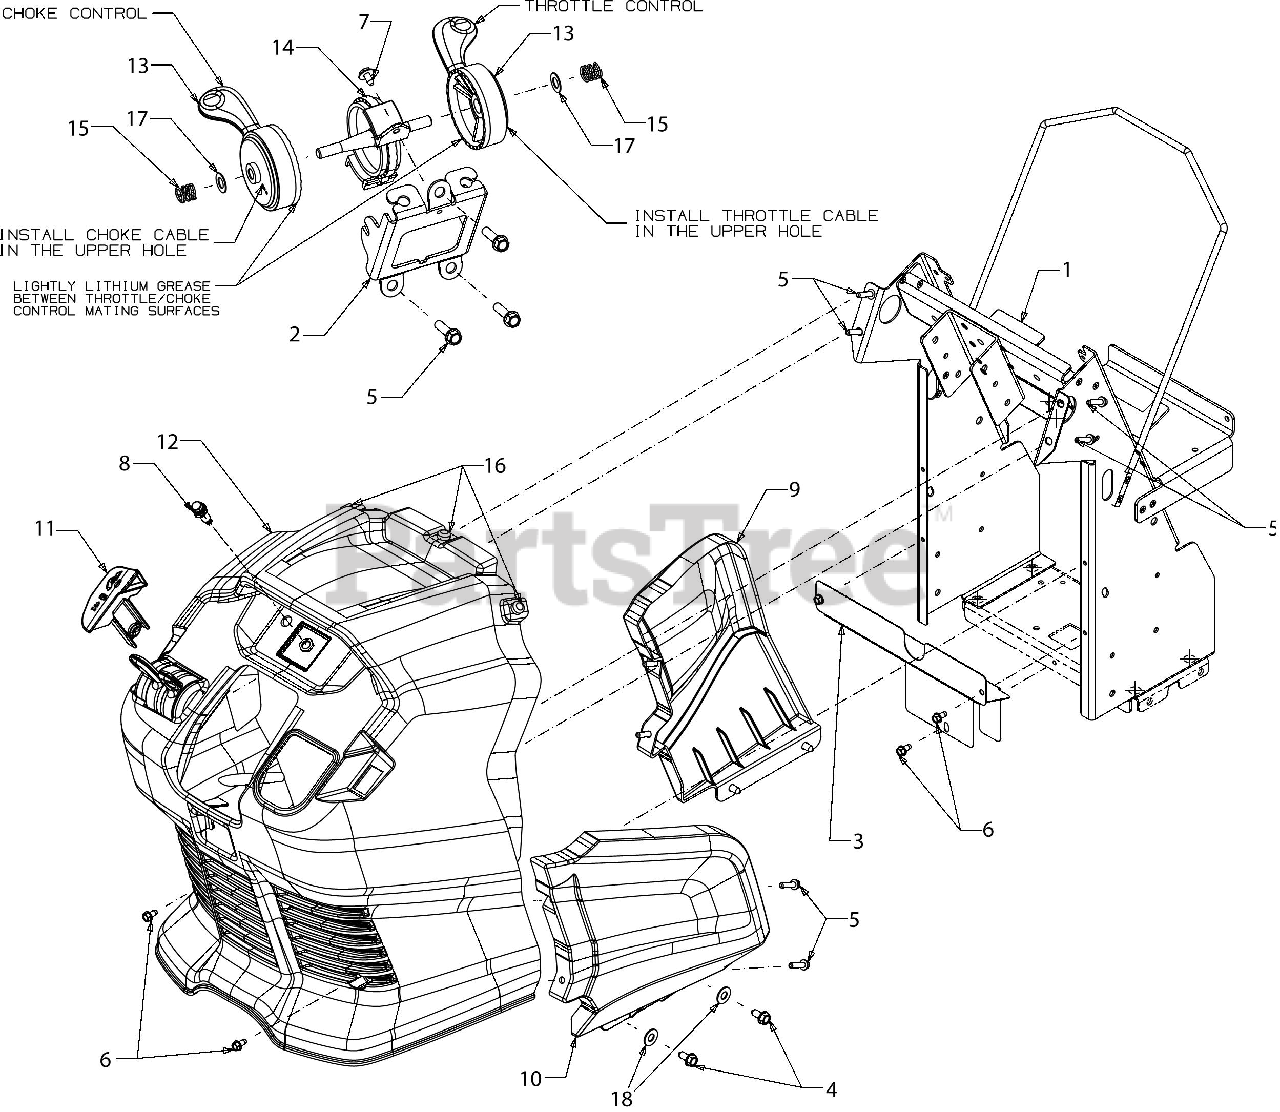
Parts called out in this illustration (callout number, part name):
2	THROTTLE/CHOKE MOUNT BRACKET
3	AIR SHIELD
4	SCREW 5/16-18 x .750
5	SCREW 5/16-14 x 1
6	SCREW 1/4-20 X.500
7	SCREW #10-16 x .375
8	INDICATOR LED LIGHT-YELLOW
9	DASH PANEL LOWER (LH)
10	DASH PANEL LOWER (RH)
11	CRUISE/PARK BRAKE LEVER
12	DASH PANEL
13	THROTTLE/CHOKE CONTROL LEVER
14	THROTTLE/CHOKE INDEX DISC
15	COMPRESSION SPRING
16	BUMPER, .62 DIA x .3
17	FLAT WASHER .344 ID x .62 OD x .033
18	FLAT WASHER
